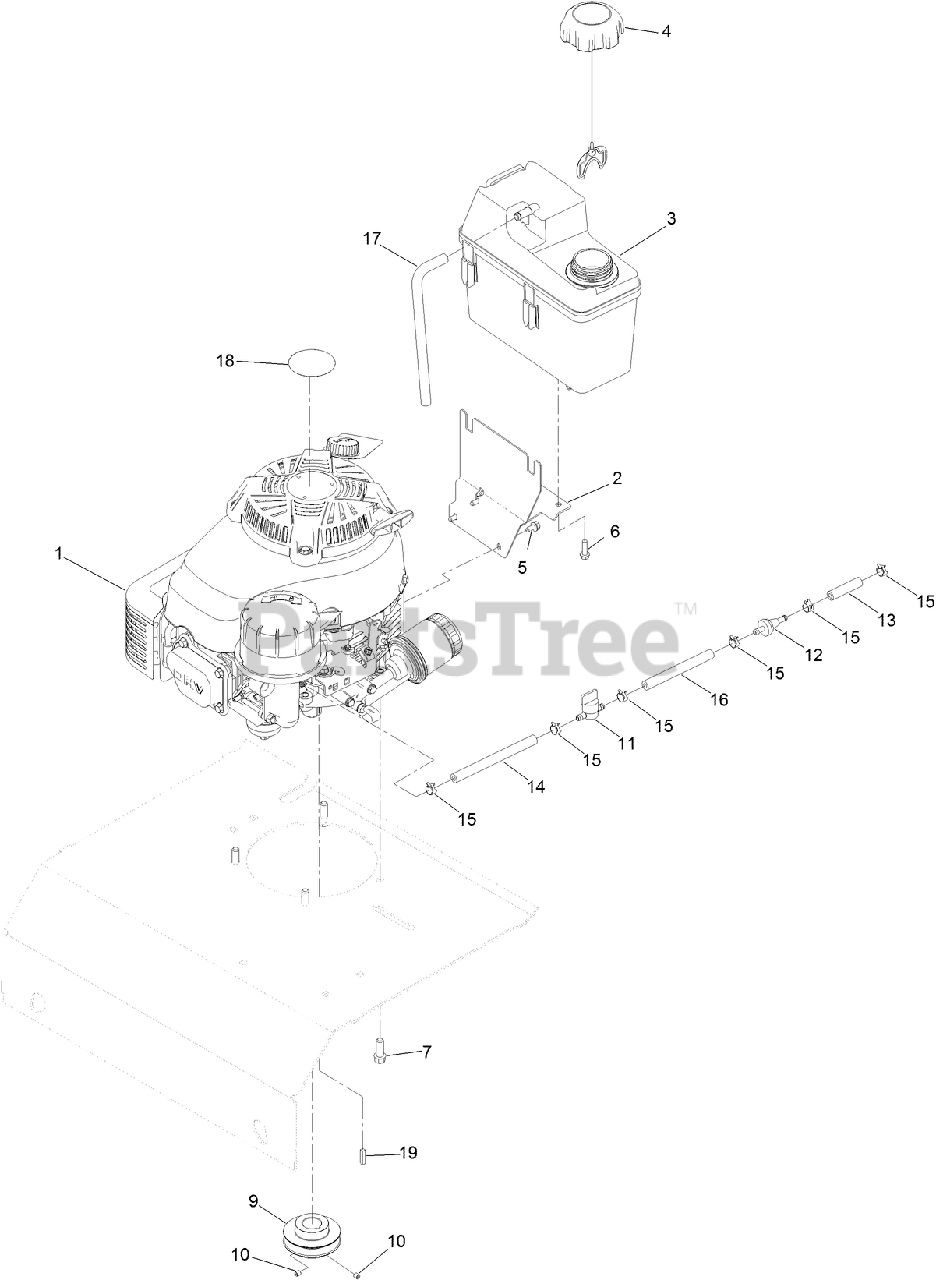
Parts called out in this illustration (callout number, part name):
2	MOUNT-TANK
3	TANK-FUEL
4	CAP-FUEL
5	SCREW-HWH
6	SCREW-HWH
7	SCREW-TAPTITE
9	PULLEY-DRIVER
10	SCREW-SET, HSH
11	VALVE-FUEL
12	FILTER-FUEL
13	HOSE-FUEL
14	HOSE-FUEL
15	CLAMP-HOSE
16	HOSE-FUEL
17	HOSE-VENT, CANISTER
19	KEY
